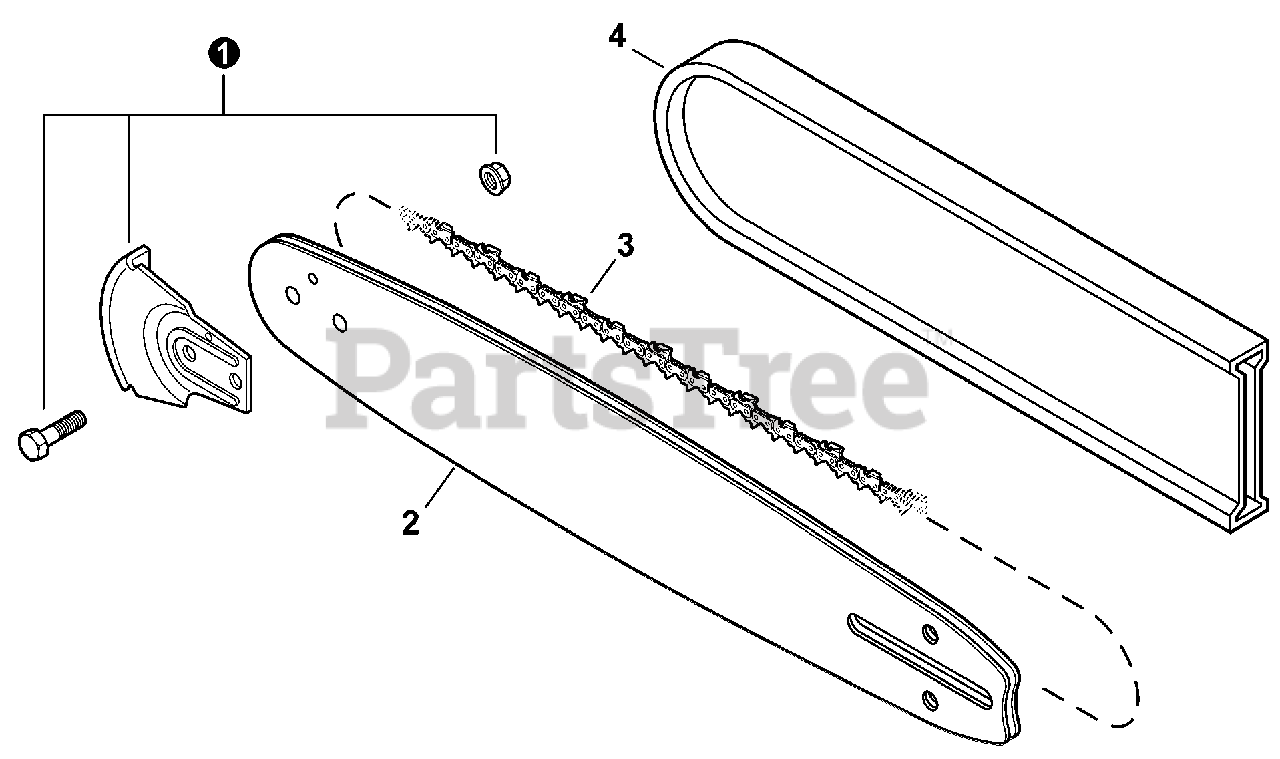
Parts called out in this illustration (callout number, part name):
1	KICK GUARD KIT
2	GUIDE BAR, 12" DOUBLE-GUARD
2	GUIDE BAR, 14" DOUBLE-GUARD
2	GUIDE BAR, 16" DOUBLE-GUARD
3	SAW CHAIN 12"
3	SAW CHAIN 14"
3	SAW CHAIN 16"
4	SCABBARD 12"-20"
